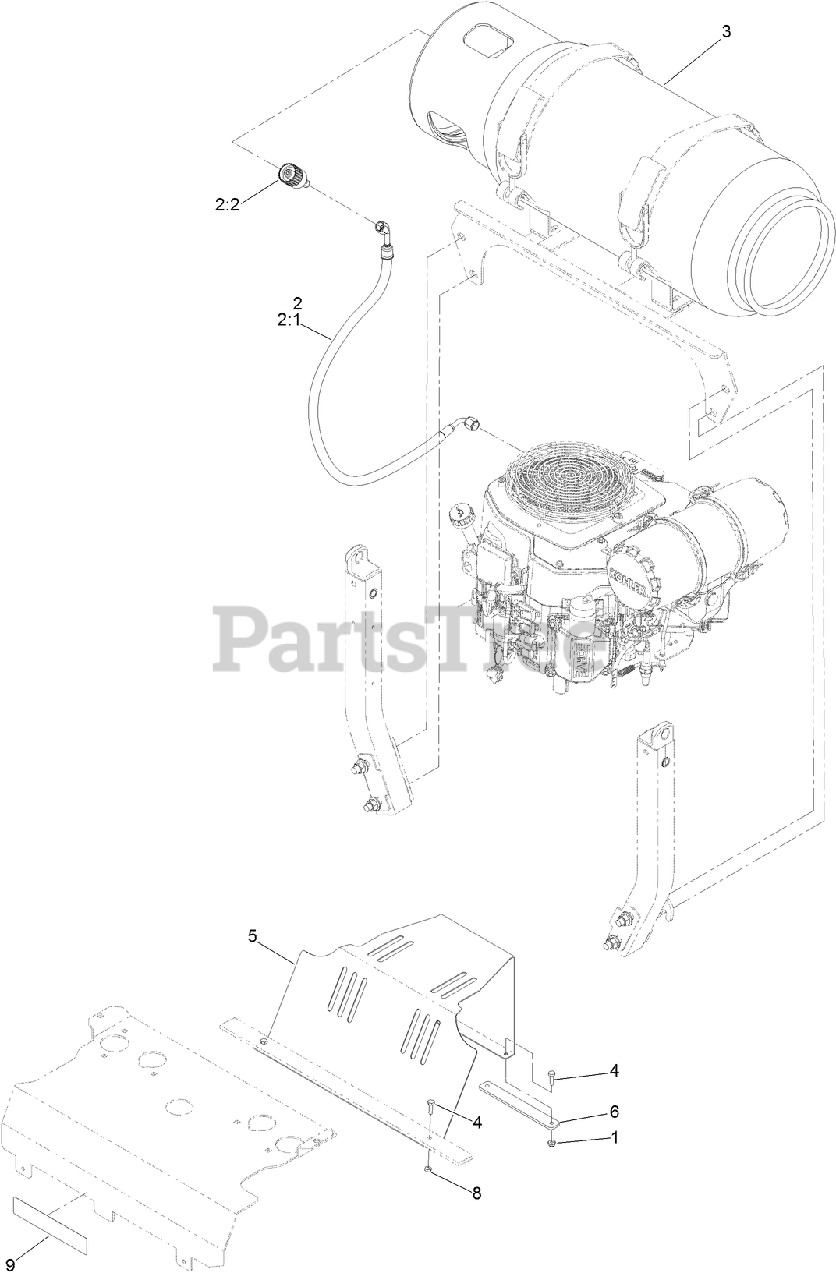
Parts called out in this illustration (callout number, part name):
1	NUT-HF
2	LPG HOSE ASM
2:1	HOSE ASM, LPG
2:2	CONNECTOR-LP, STRAIGHT
3	TANK-LPG
4	SCREW-HH
5	SHEILD-FAN
8	NUT-JAM
9	DECAL-EFI PROPANE
